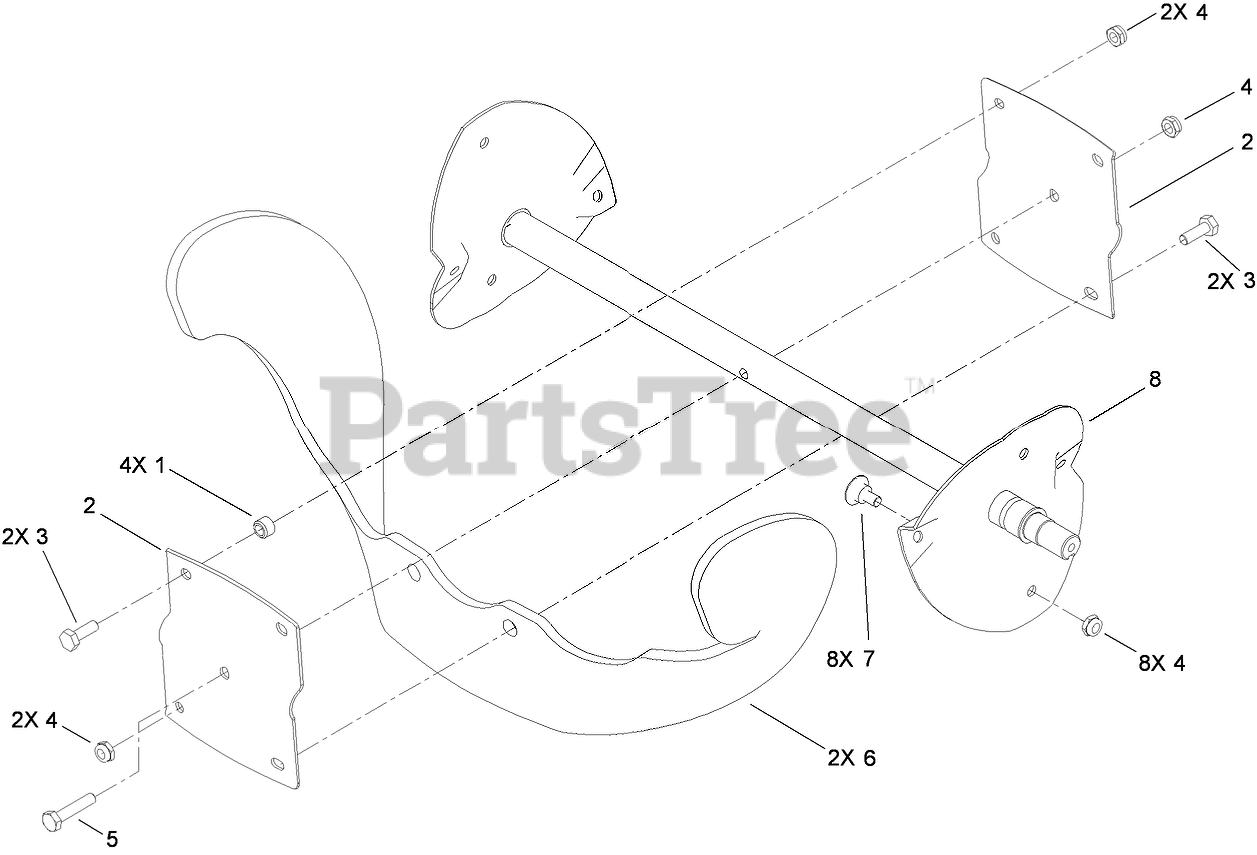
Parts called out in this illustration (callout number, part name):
1	SPACER-BLADE, ROTOR
2	HALF-ROTOR
3	SCREW-HH
4	NUT-LOCK, NI
5	SCREW-HH
6	BLADE-ROTOR
7	SCREW
8	ROTOR
